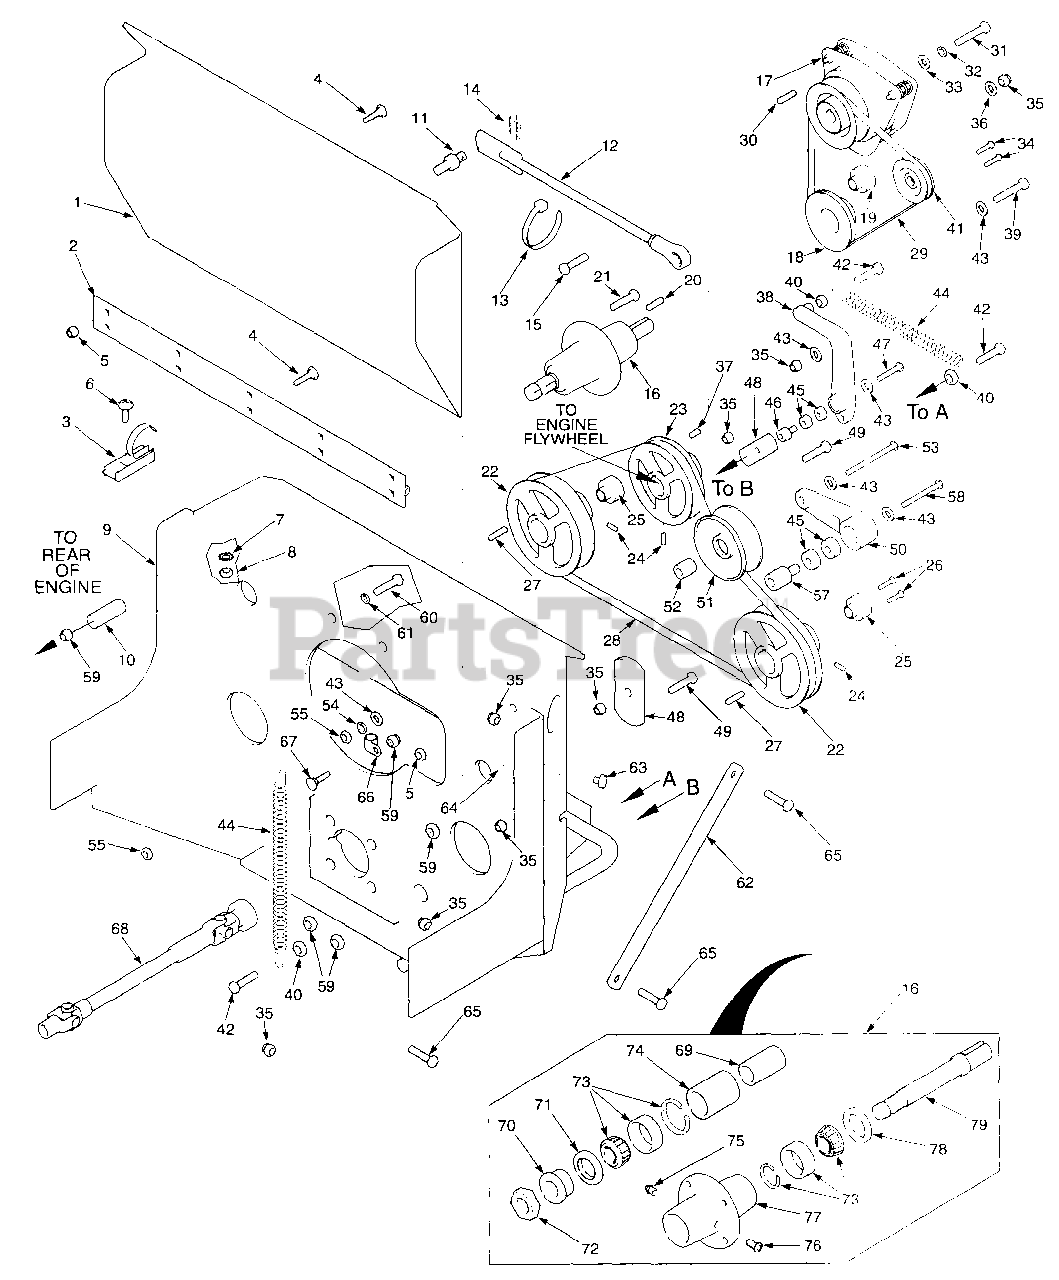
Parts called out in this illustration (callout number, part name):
1	Belt Guard, Rear
2	Hinge, Rear Belt Guard
3	Latch, Hood
4	Carr. Bolt 1/4-20 x .5"
5	Nut, Serr. Flg. 1/4-20
6	Screw, #10-32 x .5, Phillips Head
7	Lock Washer, #10
8	Nut, #10-32
9	Weldment, Pump Mounting
10	Spacer, Engine
11	Stud, Anti-Rotation
12	Rod, Anti-Rotation
13	Tie, Cable
14	Pin, Rue
15	Bolt, Hex Head 3/8-16 x 1.50"
16	Spindle Assembly, Deck Drive
17	Clutch, Electric PTO
18	Pulley, 6.35" dia. Tapered Bore
19	Hub, Tapered 1" dia.
20	Key, 1/4 x 1/4 x 1.5"
21	Bolt, Hex Head 5/16-18 x 1.25"
22	Pulley, 6.25" OD, Tapered
23	Pulley, 5.45" OD
24	Set Screw, 5/16-18 x .375"
25	Hub, Tapered 17mm Bore
26	Bolt, Hex Head 1/4-20 x .75"
27	Key, 5mm x 5mm x 30mm
28	Belt, Pump Drive
29	Belt, Deck Drive
30	Key, 1/4 x 1/4 x 2.5"
31	Bolt, Hex Head 7/16-20 x 2.5"
32	Lock Washer 7/16"
33	Flat Washer 7/16 x .469 x 1.75 x .25"
34	Bolt, Hex Head 1/4-20 x 1.375"
35	Nut, Elastic Stop 3/8-16
36	Flat Washer 3/8, .391 x .938 x .105"
37	Key, 1/4 x 1/4 x 1.00"
38	Idler Arm
39	Bolt, Hex Head 3/8-16 x 2.25"
40	Nut, Serr. Flg. 3/8-16
41	Pulley, PTO Idler
42	Bolt, Hex Head 3/8-16 x 1.5" Grade 8
43	Flat Washer 3/8" Grade 8
44	Spring
45	Bearing
46	Pivot, Idler - Short
47	Bolt, Hex Head 3/8-16 x 2.5"
48	Base, Idler Pivot
49	Bolt, Hex Head 5/16-18 x 1.00"
50	Idler Arm
51	Pulley, Pump Idler
52	Spacer
53	Bolt, Hex Head 3/8-16 x 3.75" Grade 8
54	Lock Washer 3/8" .638 x .380 x .094"
55	Nut 3/8-16
57	Pivot, Idler - Long
58	Bolt, Hex Head 3/8-16 x 3.00"
59	Nut, Elastic 5/16-18
60	Bolt, Hex Head 5/16-18 x 3.00"
61	Lock Washer 5/16"
62	Brace, Engine Mounting Plate
63	Bumper, Rubber
64	Nut, Serr. Flg 5/16-18
65	Bolt, Hex Head 3/8-16 x 1.00"
66	Clamp, Wire
67	Bolt, Carr. 5/16-18 x .75"
68	Driveshaft
69	Spacer, Inside
70	Bushing
71	Seal, 2.00 OD x 1.625 Bore
72	Nut, 1.06-18
73	Roller Bearing Assembly
74	Spacer, Outside
75	Grease Fitting 1/4-28 Self Tapping
76	Relief Fitting
77	Spindle Housing
78	Seal, 2.00 OD x 1.5 Bore
79	Shaft, Spindle
